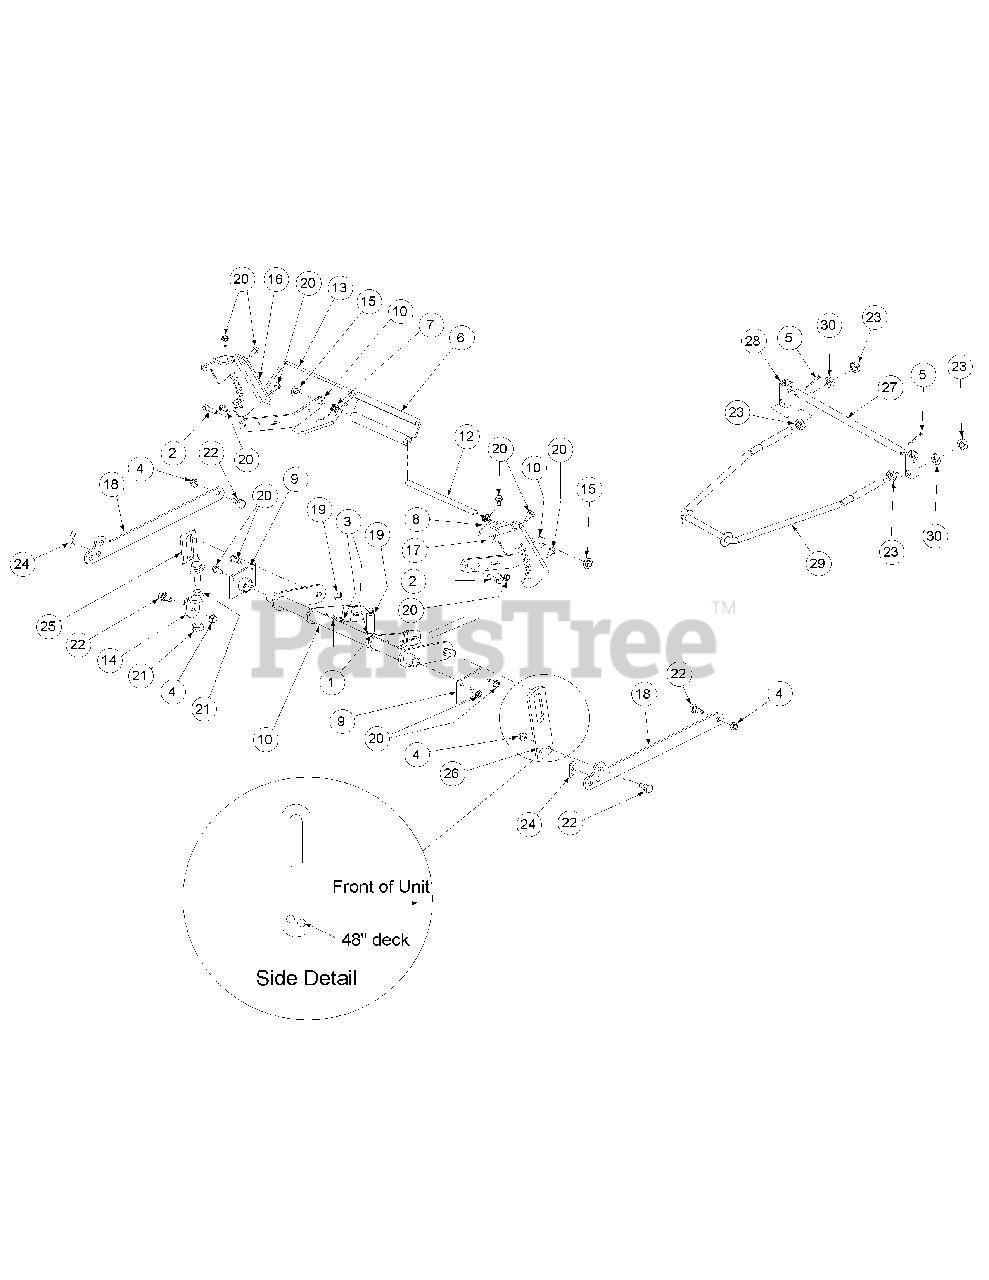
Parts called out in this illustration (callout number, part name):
1	Hex Nut, 5/16-18
2	Hex Cap Screw, 5/16-18 x 1-1/2
3	Nut, 5/16-18, Center Lock
4	Nut, 3/8-16, Hex Flange Lock
5	Cotter Pin, 3/16 x 1-1
6	Deck Lift Handle
7	Deck Lift Spring, Left Hand
8	Deck Lift Spring, Right Hand
9	Lift Hub Assembly
10	Lift Shaft Assembly
11	Handle Lift Arm
12	Lift Handle Rod
13	Lift Rod Index
14	Lower Lift Bracket, Left Hand
15	Cap Lift Push Nut
16	Lift Index Weldment, Left Hand
19	Lift Spring
20	Self Tapping Screw, 5/16-18 x 3/4
21	Jam Nut, 1/2-20
22	Shoulder Screw, 3/8-16, .56 x .27
23	Jam Nut, 5/8-11
24	Hair Pin
25	Upper Link Lift Assembly, Left Hand
26	Link Lift PLate, Right Hand
27	Front Lift Rod
28	Front Lift Rod Tube
29	Front Lift Rod
30	Lock Washer, 5/8
